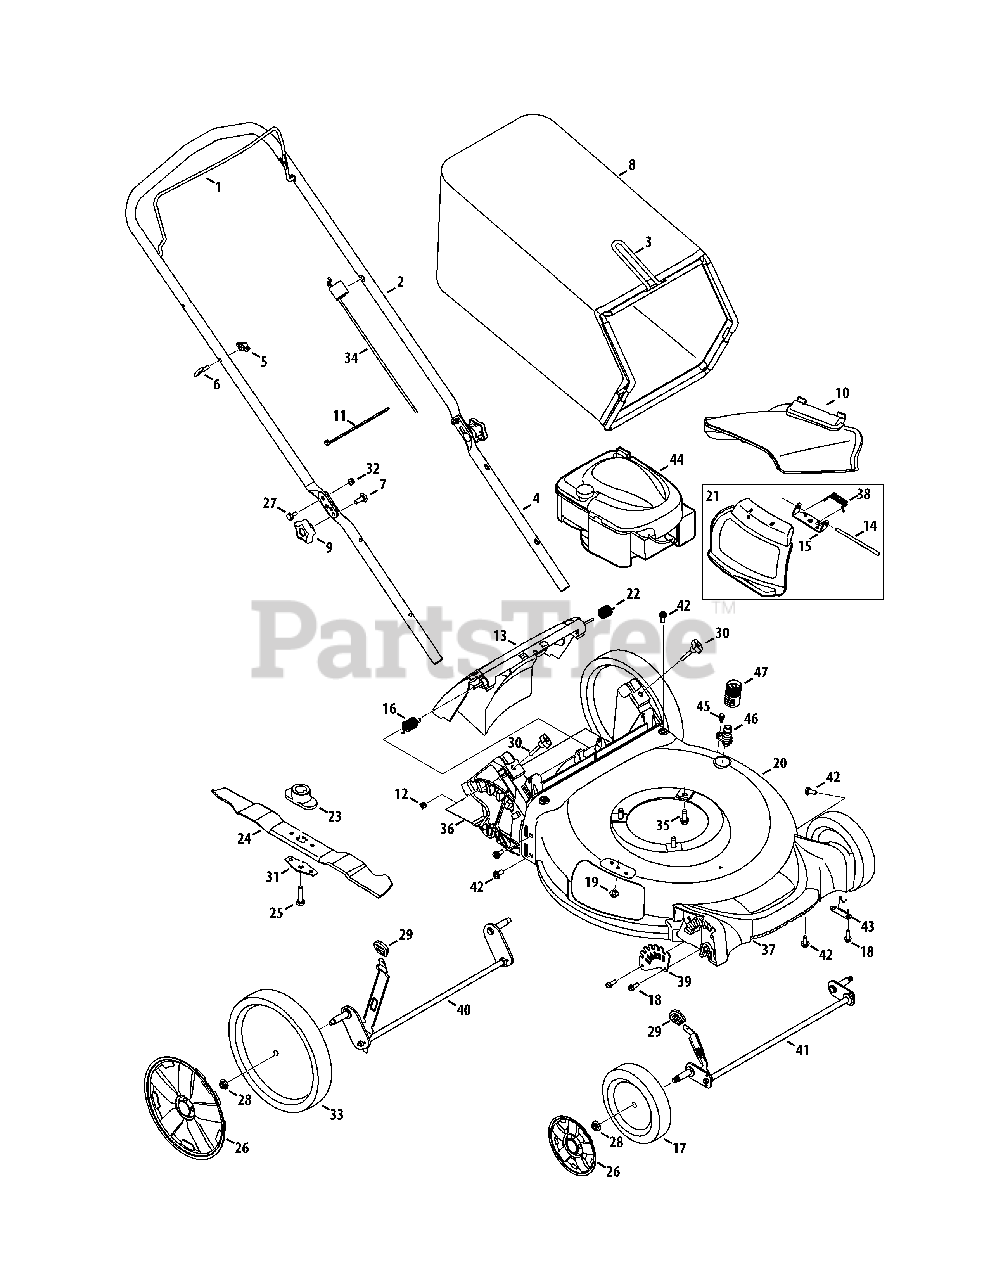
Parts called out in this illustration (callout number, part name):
1	Blade Control
2	Upper Handle
4	Lower Handle
5	Wing Nut
6	Rope Guide
7	Carriage Screw ,5/16-18
8	Grass Bag
9	Hand Knob
10	Side Chute
11	Cable Tie
12	Nut, Sq., 1/4-20
13	Rear Discharge Door Assembly
14	Hinge Pin
15	Chute Deflector Bracket
16	Torsion Spring - RH
17	Wheel, 7 x 2
18	Screw, 1/4-15 x .750
19	Screw, 1/4-20 x .500
20	Deck - 21"
21	Hinged Mulch Plug Assembly
22	Torsion Spring - LH
23	Blade Adapter
24	Mulching Blade
25	Screw , 3/8-24 x 1.50
26	Hub Cap - Front
26	Hub Cap - Rear
27	Sldr. Screw, .375 x .126 x 1/4-20
28	Flange Lock Nut, 3/8-16
29	Adjustment Lever Knob
30	Wing Nut
31	Blade Bell Support
32	Nut, Flange Lock, 1/4-20
33	Wheel, 11 x 2
34	Control Cable
35	TT Sems Screw, 3/8-16 x 1.0
36	Trail shield
37	Front Cover
38	Torsion Spring
39	Front Height Adjuster Plate
40	Rear Axle Assembly
41	Front Axle Assembly
42	Screw, 5/16-14 x .750
43	Axle Retainer Bracket
44	Engine - 128L02-0867-F1
45	Screw, 1/4-20 x .500
46	Deck Wash Nozzle
47	Water Nozzle Adapter
